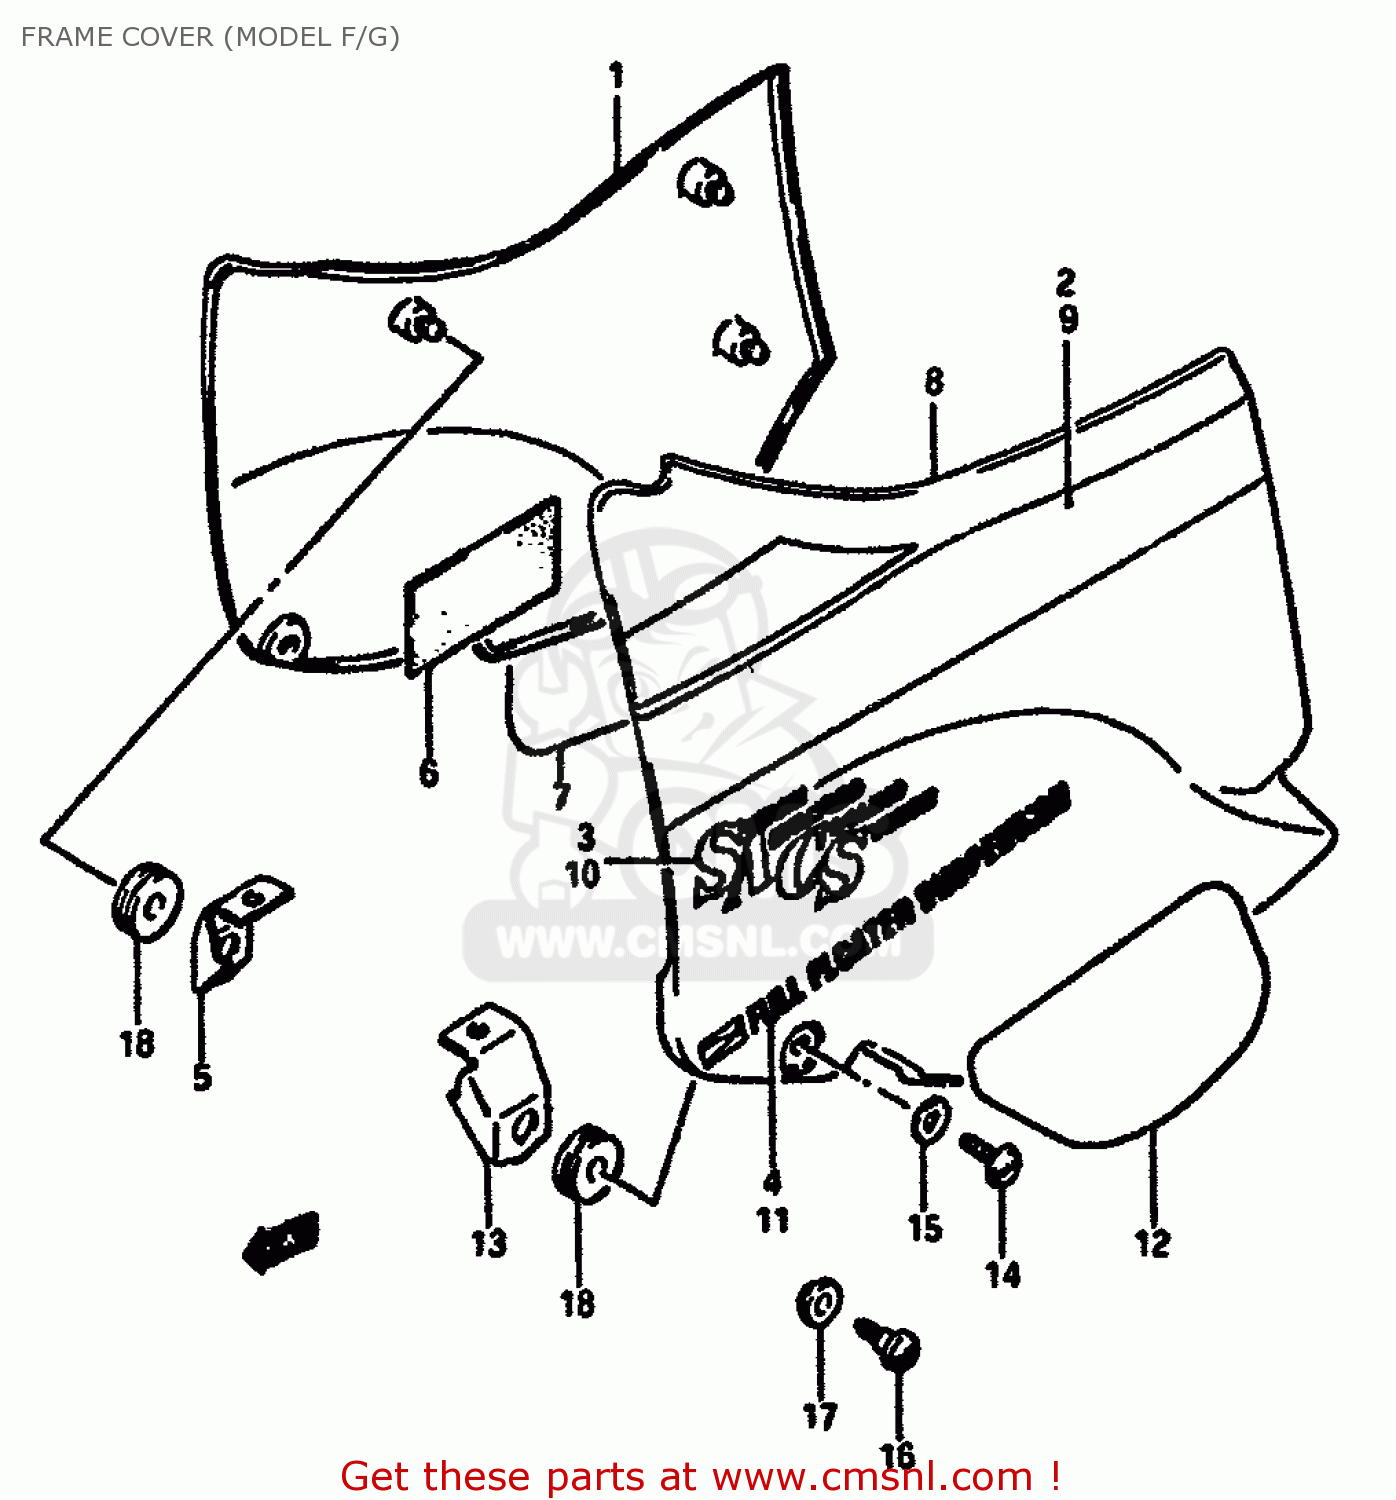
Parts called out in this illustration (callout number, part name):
1	COVER,FRAME RH
2	TAPE SET,RH
3	EMBLEM
4	EMBLEM
5	HOLDER,FRAME COVER RH
6	RUBBER,FRAME COVER,RIGHT
7	PROTECTOR,FRAME COVER
8	COVER,FRAME LH
9	TAPE SET,LH
10	EMBLEM
11	EMBLEM
12	PROTECTOR,FRAME COVER LH
13	HOLDER,FRAME COVER LH
14	SCREW(6X16)
15	WASHER(6.5X16X1.2)
16	SCREW(6X23)
17	CUSHION
18	CUSHION
